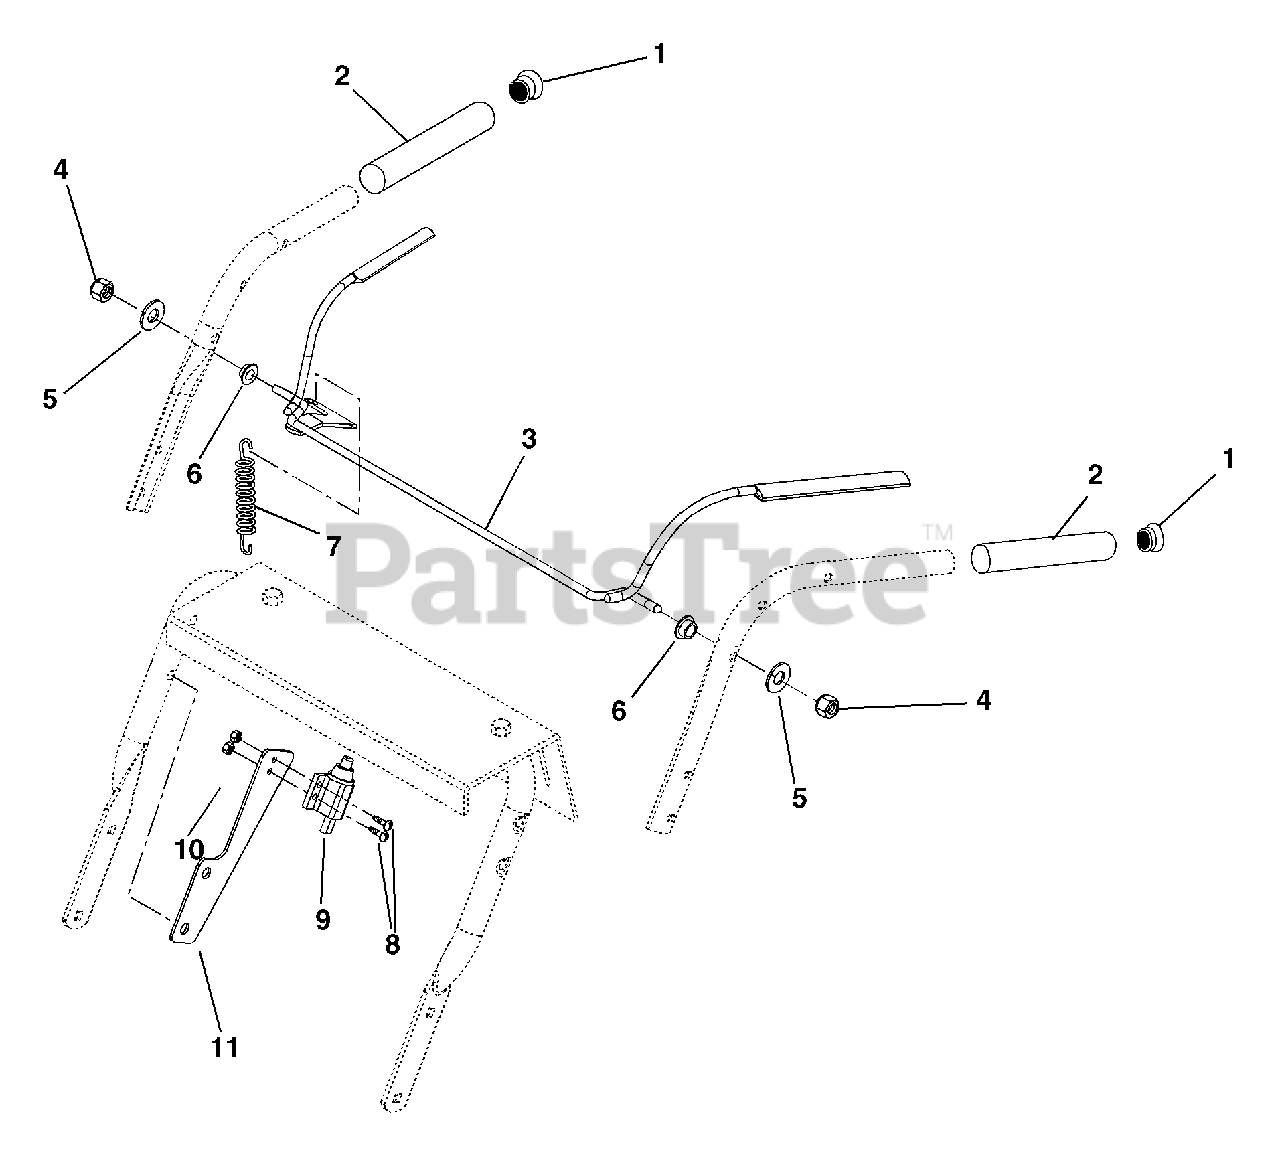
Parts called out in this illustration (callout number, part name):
1	CLOSURE,VINYL
2	GRIP, HANDLE
3	WMT, ROD (OPERATOR PRESENCE)
4	@NUT-LK-CTR .31-18 YWZC
5	@WSHR-FL-STL.344X.688X.065YWZC
6	BSHG-FLG .325X.444X.440X.560
7	SG-TENS .041X.500X1.750
8	@SCR-MCH 10-24X.75 HWH YWZC
9	SWITCH-SINGLE POLE N.O.W/COVER
10	@NUT-LK-NYL 10-24 W/INSRT YWZC
11	BRACKET, SWITCH MOUNTING
